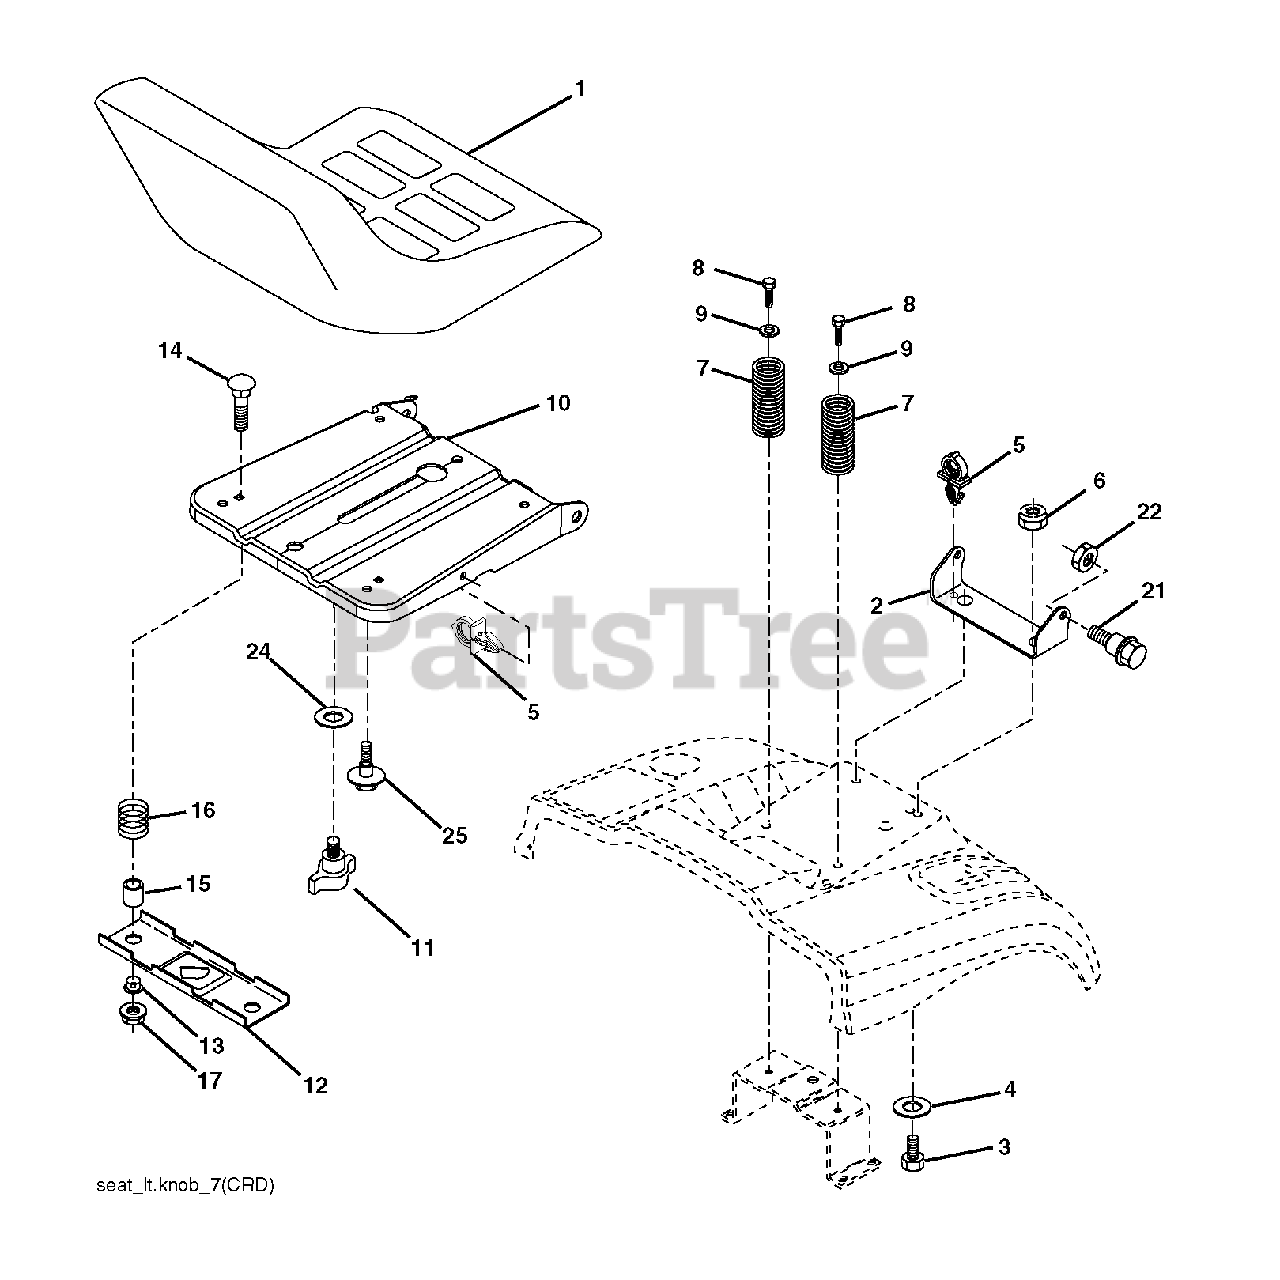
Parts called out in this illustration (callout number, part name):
1	SEAT.XG150.BLK.KB/SLD.NO-LOGO
2	SEAT PIVOT BRKT
4	WASHER PM
5	PUSH CLIP
6	NUT
7	SPRING COMPRESSION
8	SCREW 3/8-16X1
9	WASHER
10	PAN.ASM.SEAT.1SLOT
11	KNOB.SEAT.ADJ.WINGNUT
12	BRKT.MNTNG.SWITCH.SEAT
14	BOLT.ROUND.HEAD.SQUARE.NECK
15	SPACER SPLIT
16	SPRING COMPRESSED
17	NUT T
21	BOLT.SHOULDER.5/16-18
22	NUT.71038.31-18.HEX.NYLOCK
25	BOLT,SHOULD
